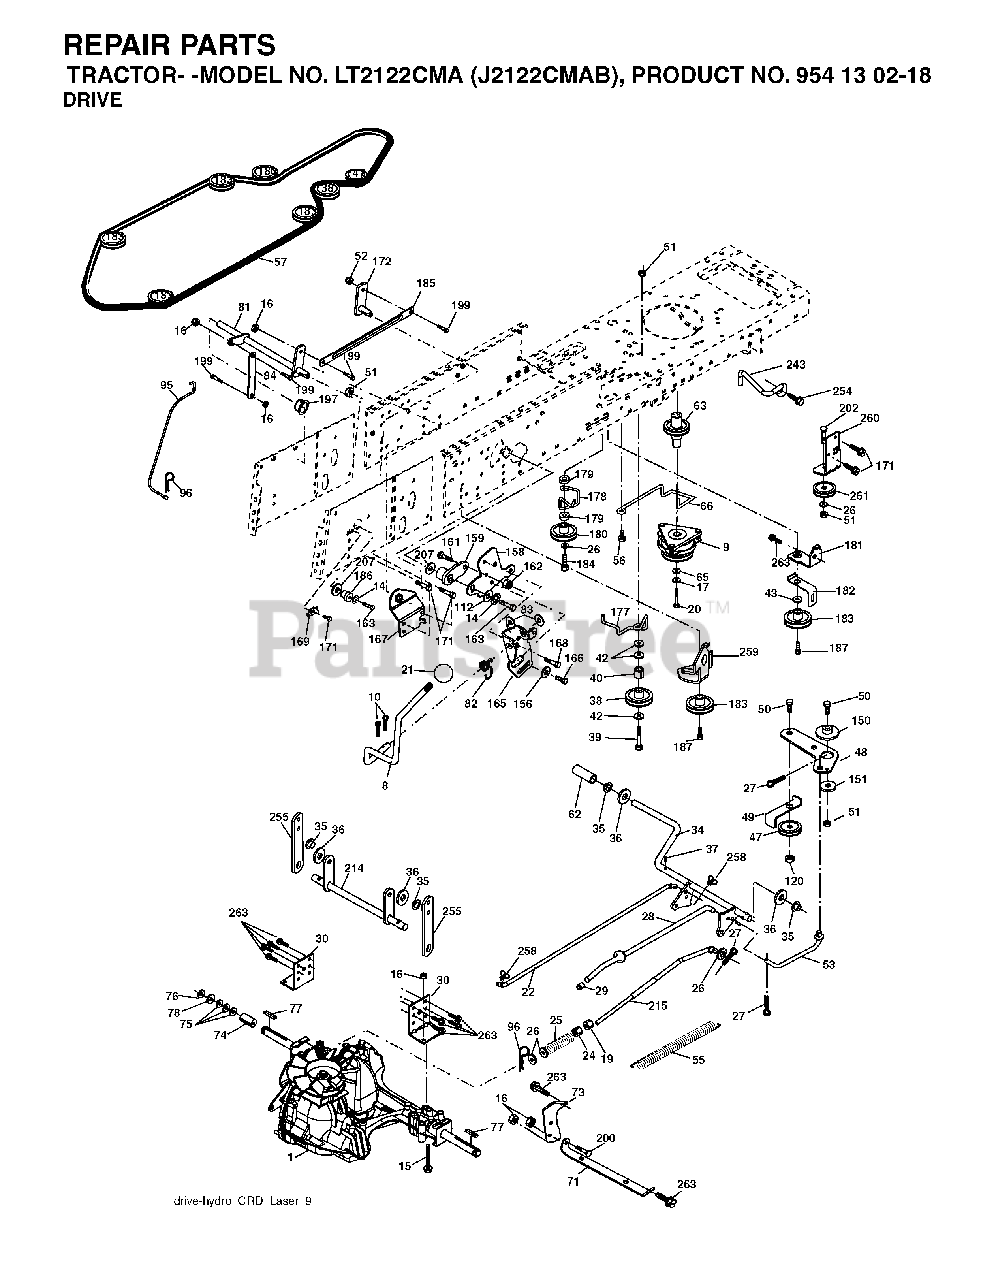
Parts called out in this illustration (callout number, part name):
8	ROD SHIFT
10	PIN COTTER
14	LOCKWASHER
16	NUT.71038.31-18.HEX.NYLOCK
17	LOCKWASHER
19	NUT
20	BOLT HEX 7/16-20X4-1/4"
21	PISTOL KNOB
24	NUT
25	SPRING ROD LT
27	COTTER PIN
28	ROD, PARKING BRAKE
29	PLUNGER CAP
30	BRKT, TRNSXLE MNT 20"
34	SHAFT, FOOT PEDAL
35	BEARING.NYLON
36	WASHER LT
37	DRIVE PIN
38	PULLEY.FLAT
42	WASHER
47	IDLER PULLEY
48	BELLCRANK, CLUTCH
49	RETAIN BELT
50	BOLT.3/8-16X1.50
51	LOCKNUT
52	LOCKNUT
53	LINK, CLUTCH LT
55	SPRING, RETURN LT
56	SCREW.3/8-16
62	PEDAL COVER T
66	KEEPER BELT ENGINE
71	STRAP TORQUE LH HYDRO
73	STRAP TORQUE RH HYDRO
74	SPACER AXLE
76	E-RING LT
77	SQUARE KEY
81	SHAFT ASSY
82	SHIFT SPRING
83	WASHER
96	RETAINER M
120	NUT LOCK FLG 3/8-16 UNC
145	BOLT HEX 5/16-18 GR 5
150	BUSHING.BELLCRANK.GRD.DR
151	WASHER 12/32X2X10GA
156	WASHER.SRRTD.5/16
158	BRACKET
159	HUB.SHIFT
161	BOLT
162	NUT.CROWNLOCK.1/4
164	WASHER LT
165	RP BRACKET
167	BRACKET
168	BOLT.SHOULDER.5/16-18X
169	PLATE.FASTENING.CROSS.SHAFT
180	PULLEY.FLAT.IDLER
184	SCREW.HXWSH.3/8
187	BOLT.5/16-18X1.25
197	NYLINER SNAP 5/8" ID
199	BOLT SHOULDER 5/16-18 UNC
200	BOLT
202	BOLT
207	WASHER NYL
243	BRACKET, ANTI-ROTATION
254	SCREW 3/8-16X1
258	CLIP RETAINER
261	FLAT IDLER PULLEY
263	SCREW, 3/8-16X3/4
